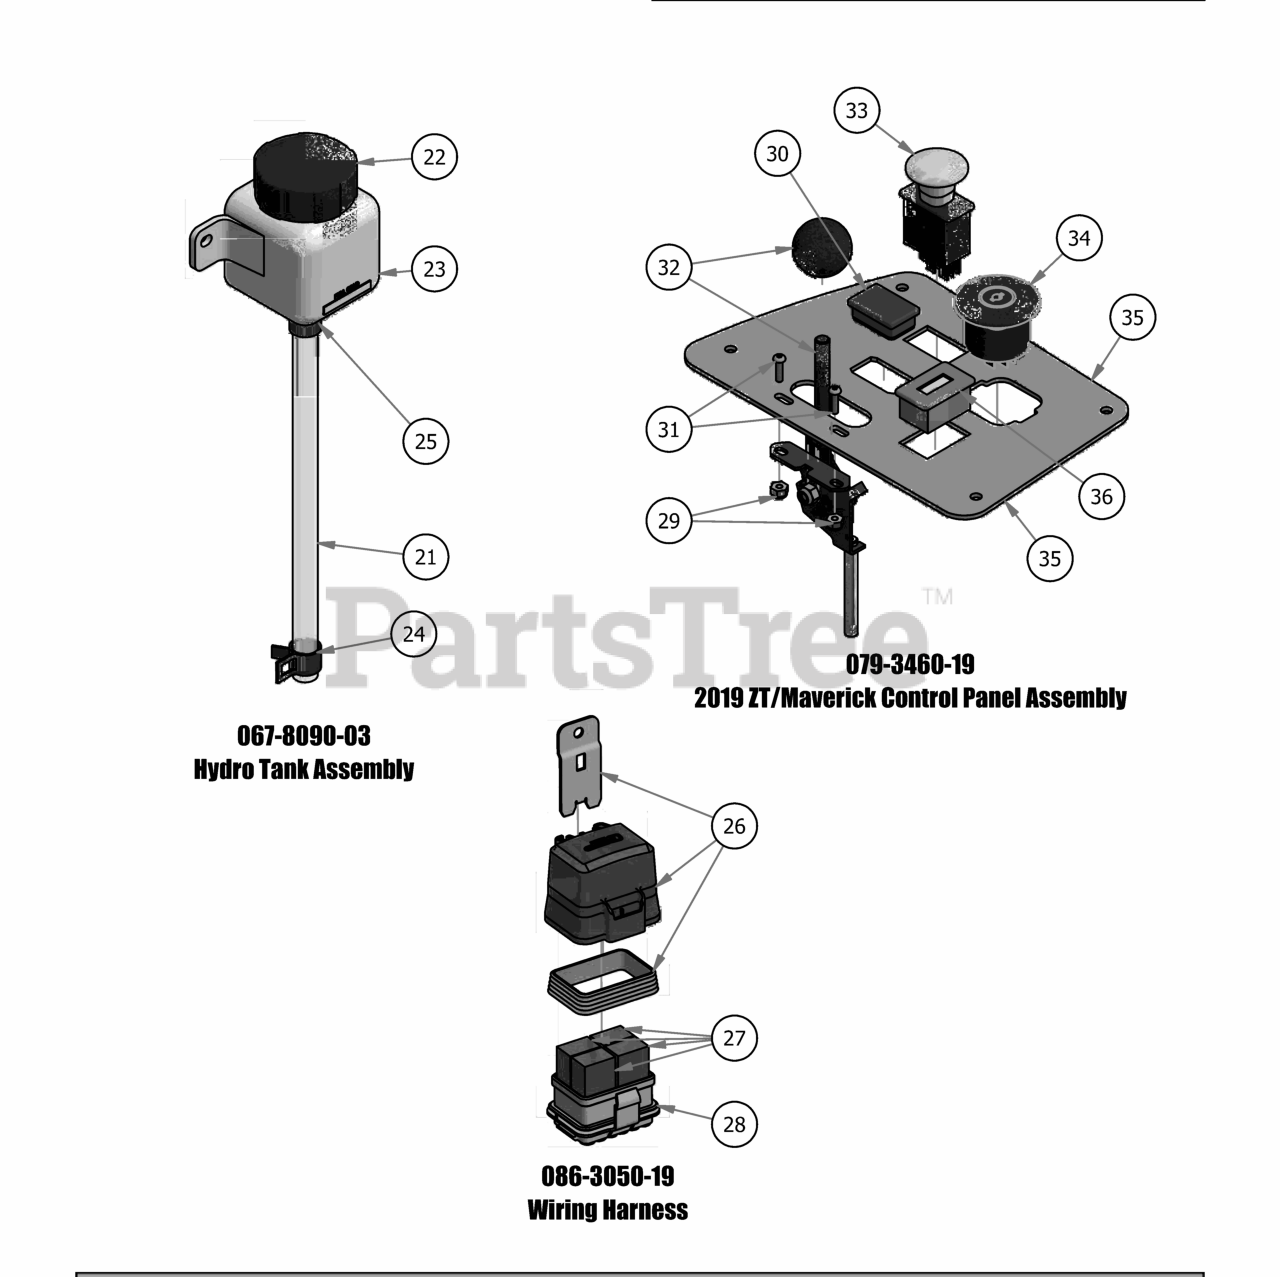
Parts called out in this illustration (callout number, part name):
21	ZT/Maverick Hydro Tank Hose
22	Hydraulic Tank Cap
23	350ml Expansion Tank
24	3/8" Hose Clamp
25	1/2 Hose Clamp
26	Relay Block Cover Replacement Kit
28	Wiring Harness
29	10-24 Nylon Insert Locknut Zinc Orange Nylon
30	Light Plug
31	10-24 X 5/8 BS Button Head Bolt
32	Throttle Lever Assembly
33	PTO Engager
34	Ignition Switch
35	Control Panel
36	Tachometer
